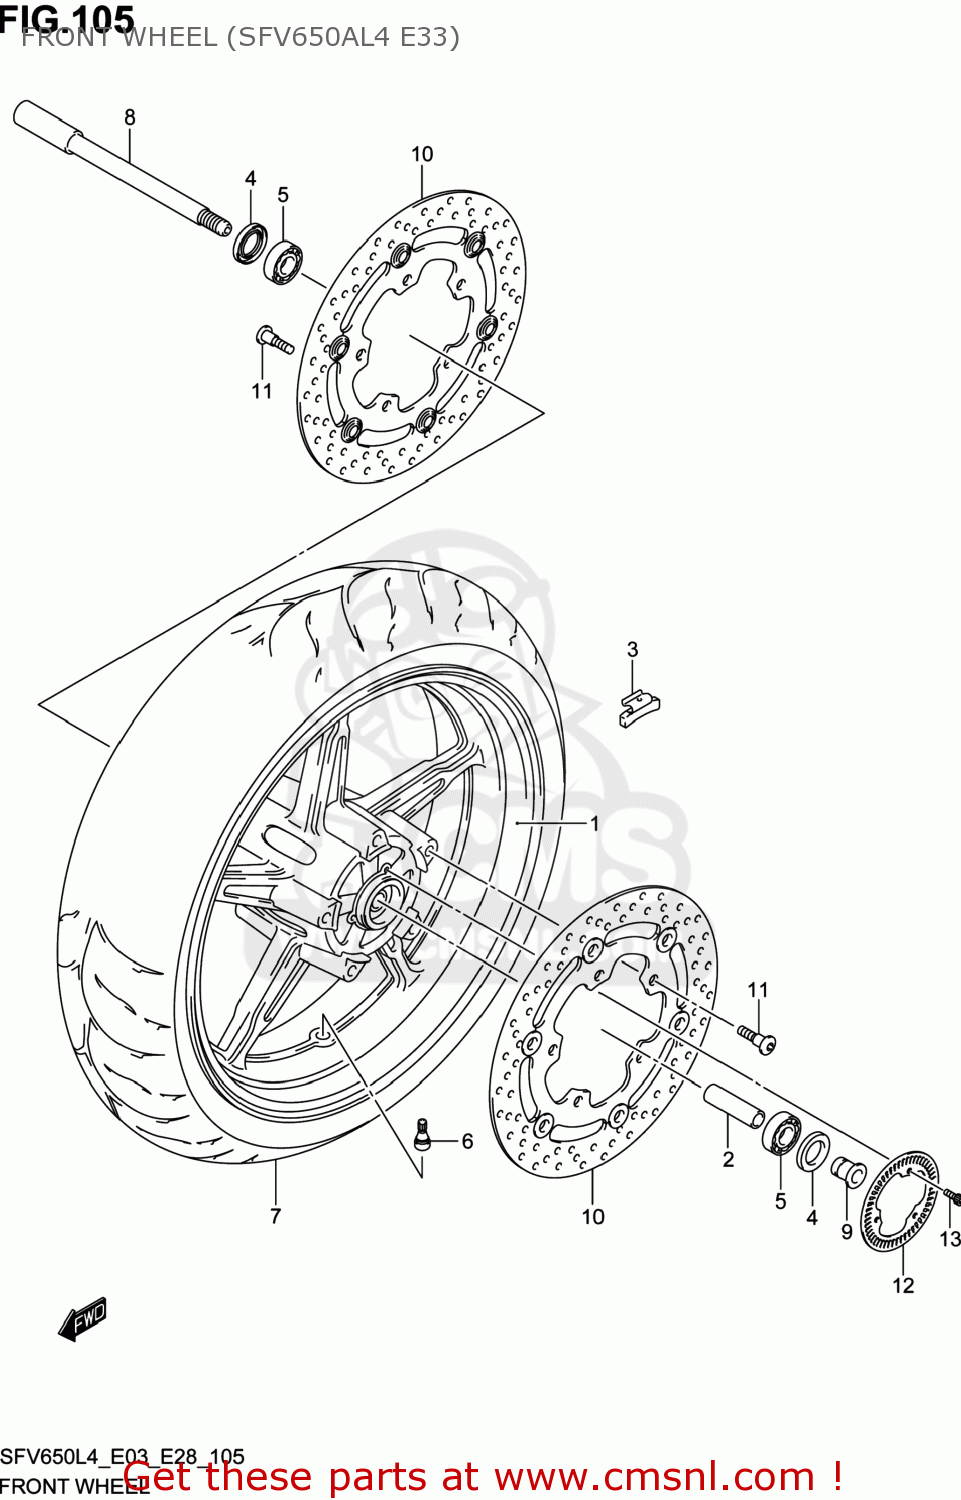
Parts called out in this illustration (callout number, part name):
1	WHEEL,FR(17M/CXMT3.50)
2	SPACER,FR HUB BEARING
3	BALANCER,WHEEL(10G)
4	SEAL,OIL(22X40X7)
5	BEARING
6	VALVE ASSY,WHEEL RIM(TR412)
7	TIRE,FRONT(120
8	AXLE,FR
9	SPACER,FR AXLE,L
10	DISC,FR BRAKE
11	BOLT(8X21)
12	RING,SPEED SENSOR FR(50T)
13	BOLT
